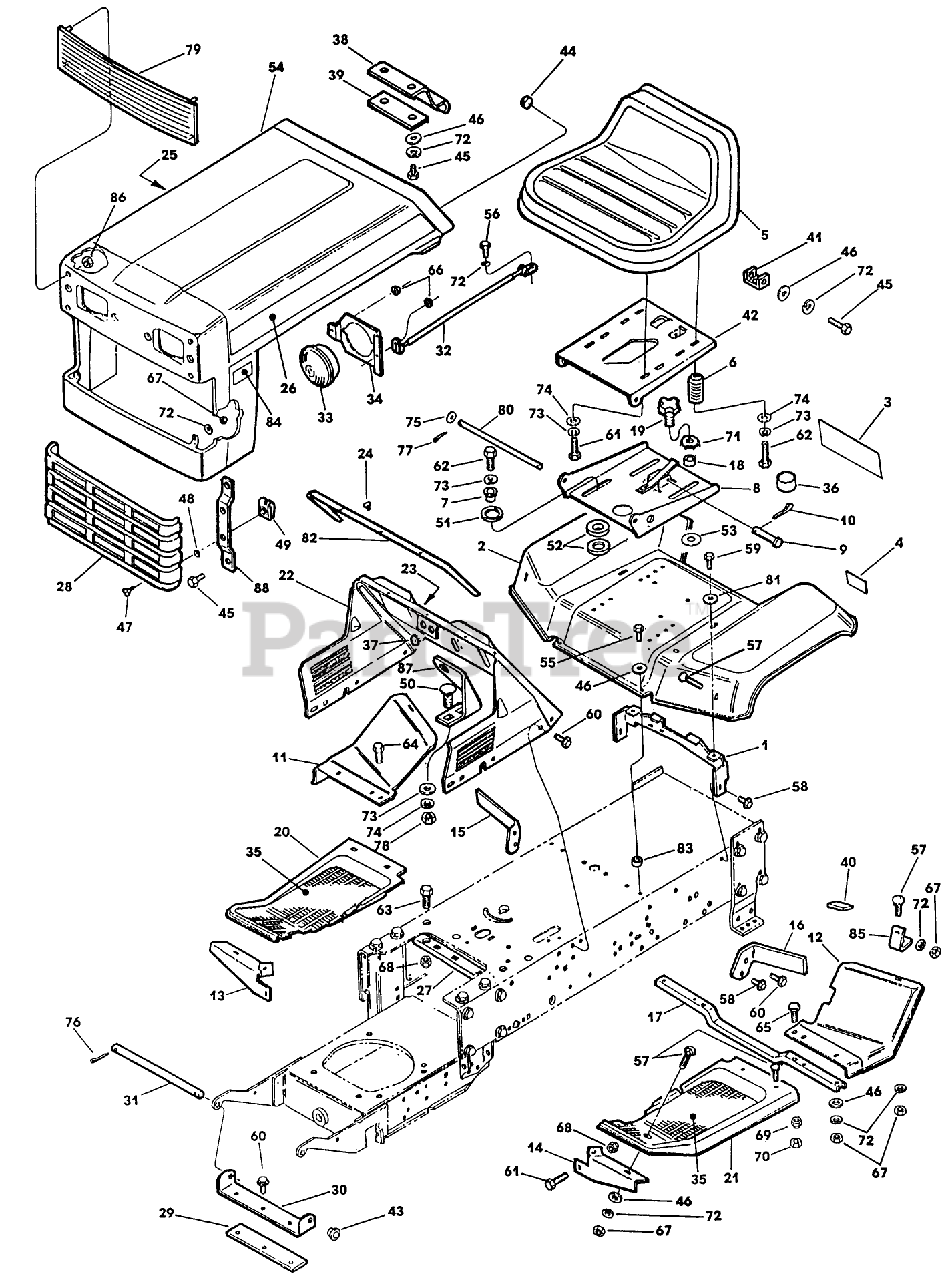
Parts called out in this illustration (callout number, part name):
1	BRACKET-SEAT SUPT
4	REFLECTOR
8	SEAT SUPPORT AY
18	SPACER
19	KNOB
22	INST PANEL & DECAL *B
26	DECAL - HOOD LH
28	INSERT - GRILLE
36	CAP-PROTECTOR
42	PIVOT AY - SEAT *B
43	BEARING-NYLINER
45	SCREW-HH
47	FASTENER-1/4 TURN
52	WASHER-PLASTIC
54	HOOD GRILLE WLDMT *G
56	SCREW
59	SCREW-HWH
61	SCREW - HEX
62	SCREW
67	NUT
68	NUT
69	NUT-LOCKING
70	NUT
75	WASHER
78	NUT SS
80	PIN
90	DECAL - HOOD LH
